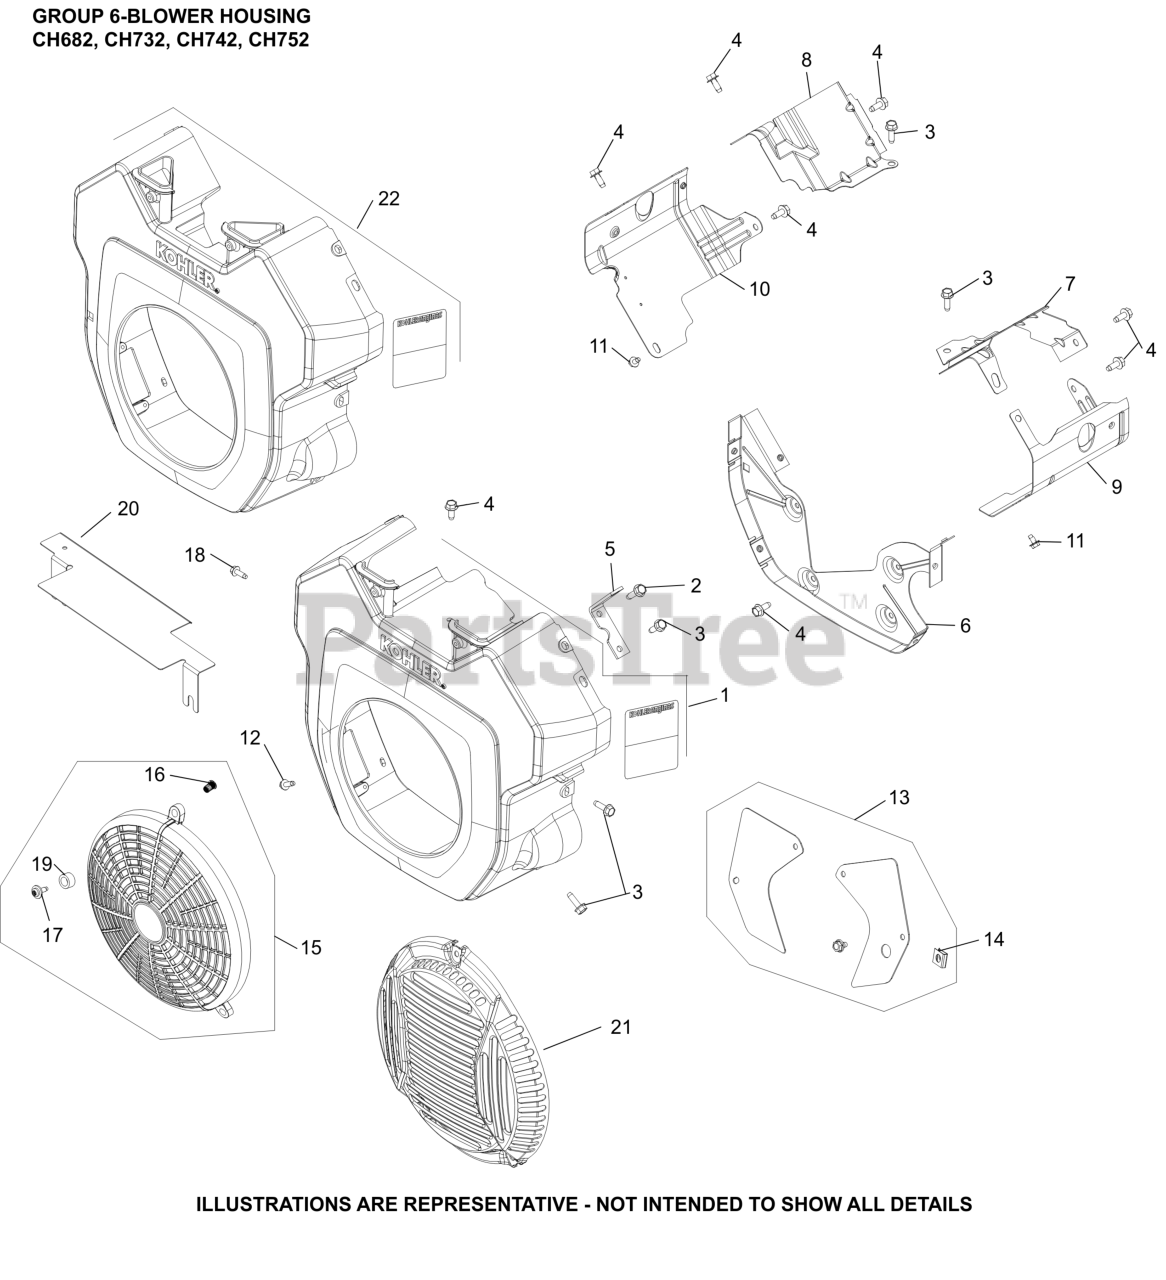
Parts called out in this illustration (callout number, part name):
1	KIT, BLOWER HOUSING
1	HOUSING, BLOWER
4	SCREW, THREAD FORMING
5	STRAP, LIFT
6	KIT, BACKING PLATE
7	BAFFLE, VALLEY #1 CYLINDER
8	BAFFLE, VALLEY #2 CYLINDER
9	KIT, CYL BAFFEL #1 SIDE
10	BAFFLE, LEFT BARREL
11	SCREW, THREAD FORMING
12	SCREW, THREAD FORMING
15	KIT, FIXED GUARD
16	INSERT, THREADED (M5)
17	SCREW, SEMS
18	SCREW, THREAD FORMING
